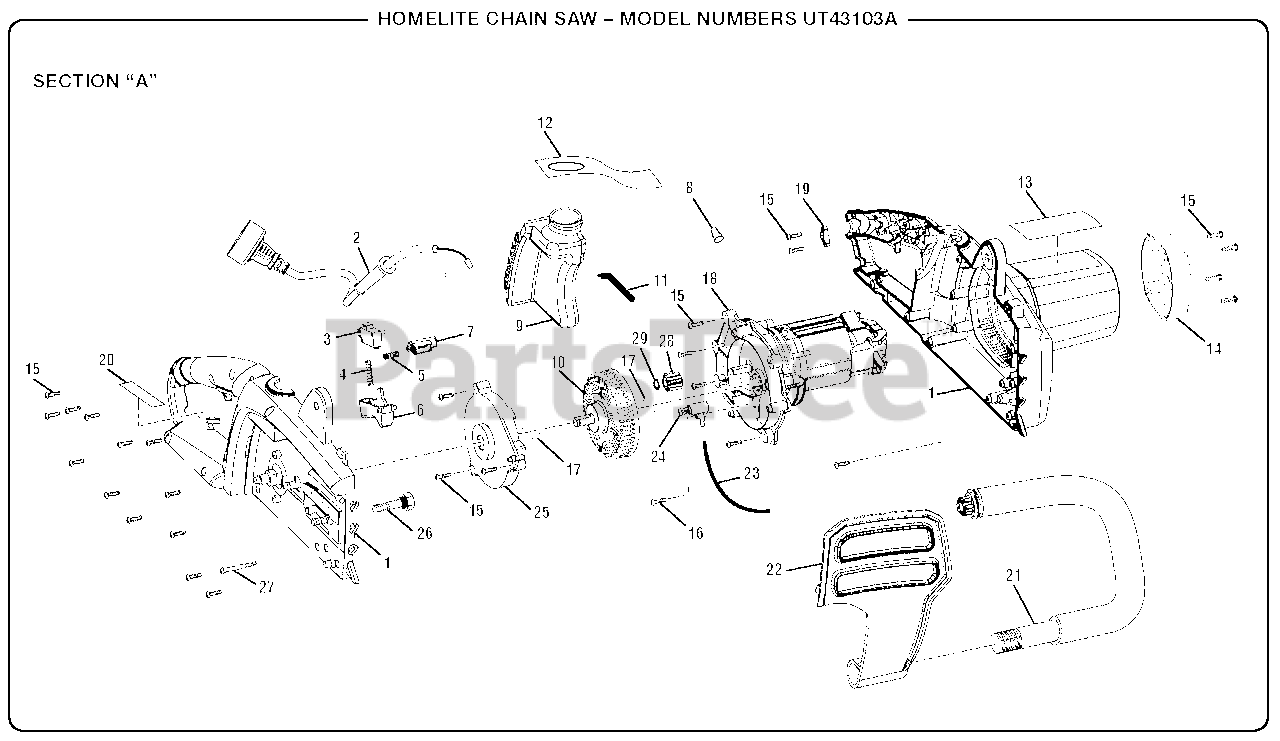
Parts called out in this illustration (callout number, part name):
1	Housing Assembly
2	Power Cord
4	Trigger Spring
5	Lock-off Spring
7	Lock-off Button
9	Oil Reservoir Assembly
10	Ring Gear Assembly
11	Inlet Oil Tube
12	Hang Tang
14	Motor Cap
15	Screw (M4 x 14 mm)
16	Screw (M3.8 x 14 mm)
17	Rubber Pin
18	Motor Assembly
19	Cord Clamp
21	Front Handle
23	Outlet Oil Tube
25	Ring Gear Cover
26	Chain Bar Stud
27	Screw (M4.2 x 45 mm)
29	Retaining Ring
